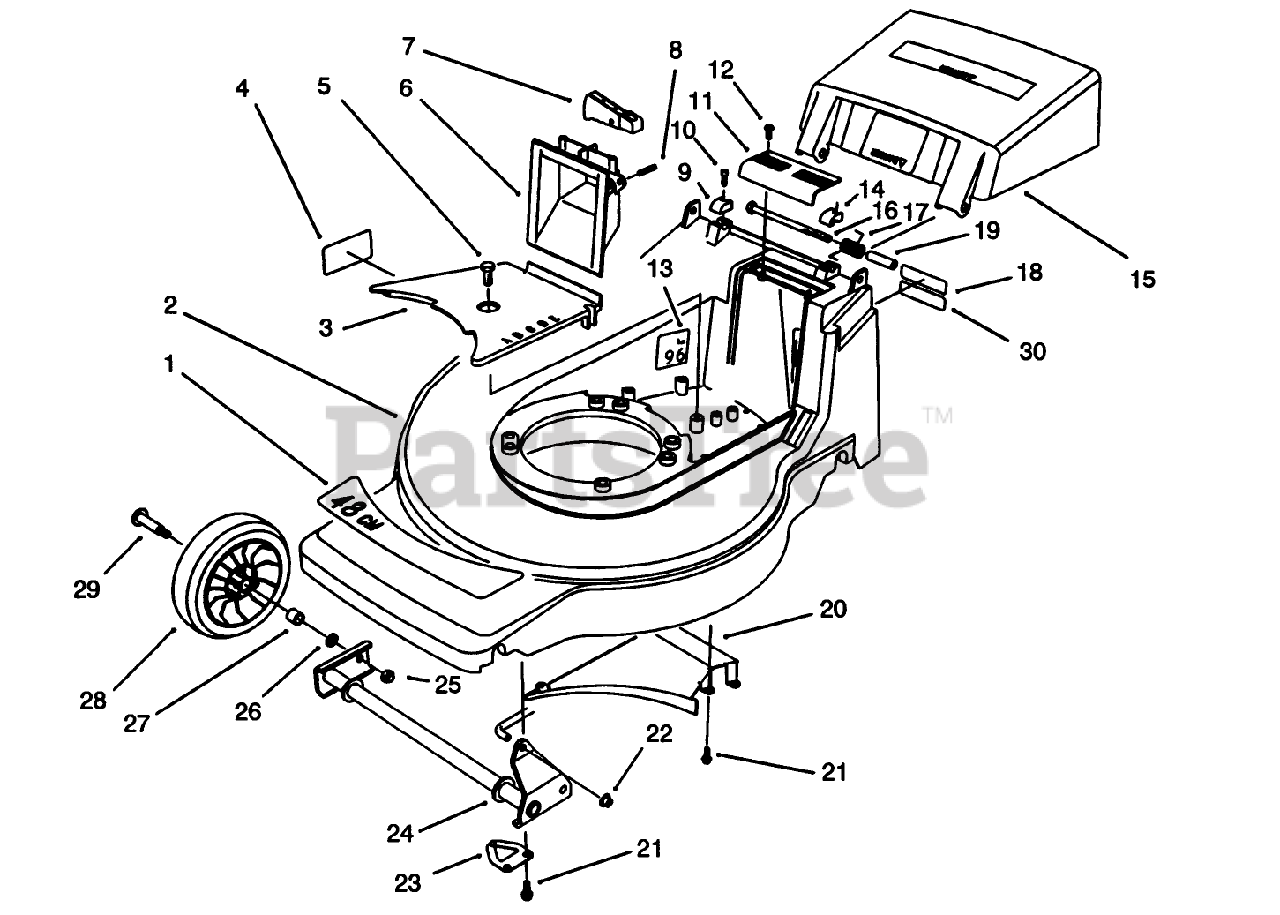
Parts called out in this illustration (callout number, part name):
2	Housing-48cm (Incl. Ref. #4)
5	SCREW-HWHTF
6	GRIP - LOWER
7	TRIGGER - HOC
9	CAP-HINGE BOLT, RH
10	SCREW-HSH
11	GRIP-UPPER
12	SCREW-PPH, PLASTITE
13	Decal-Noise Rating
14	CAP-HINGE BOLT, LH
15	HP DISCHARGE DOOR
16	SCREW-HH
17	SPRING-DOOR
19	SPACER-DOOR
21	SCREW-HWH
22	NUT-PUSH
23	SHAFT RETAINER ASM
24	FRONT PIVOT WA
25	NUT-HEX
26	WASHER
27	BUSHING
29	BOLT-WHEEL
30	Decal-Power Rating
